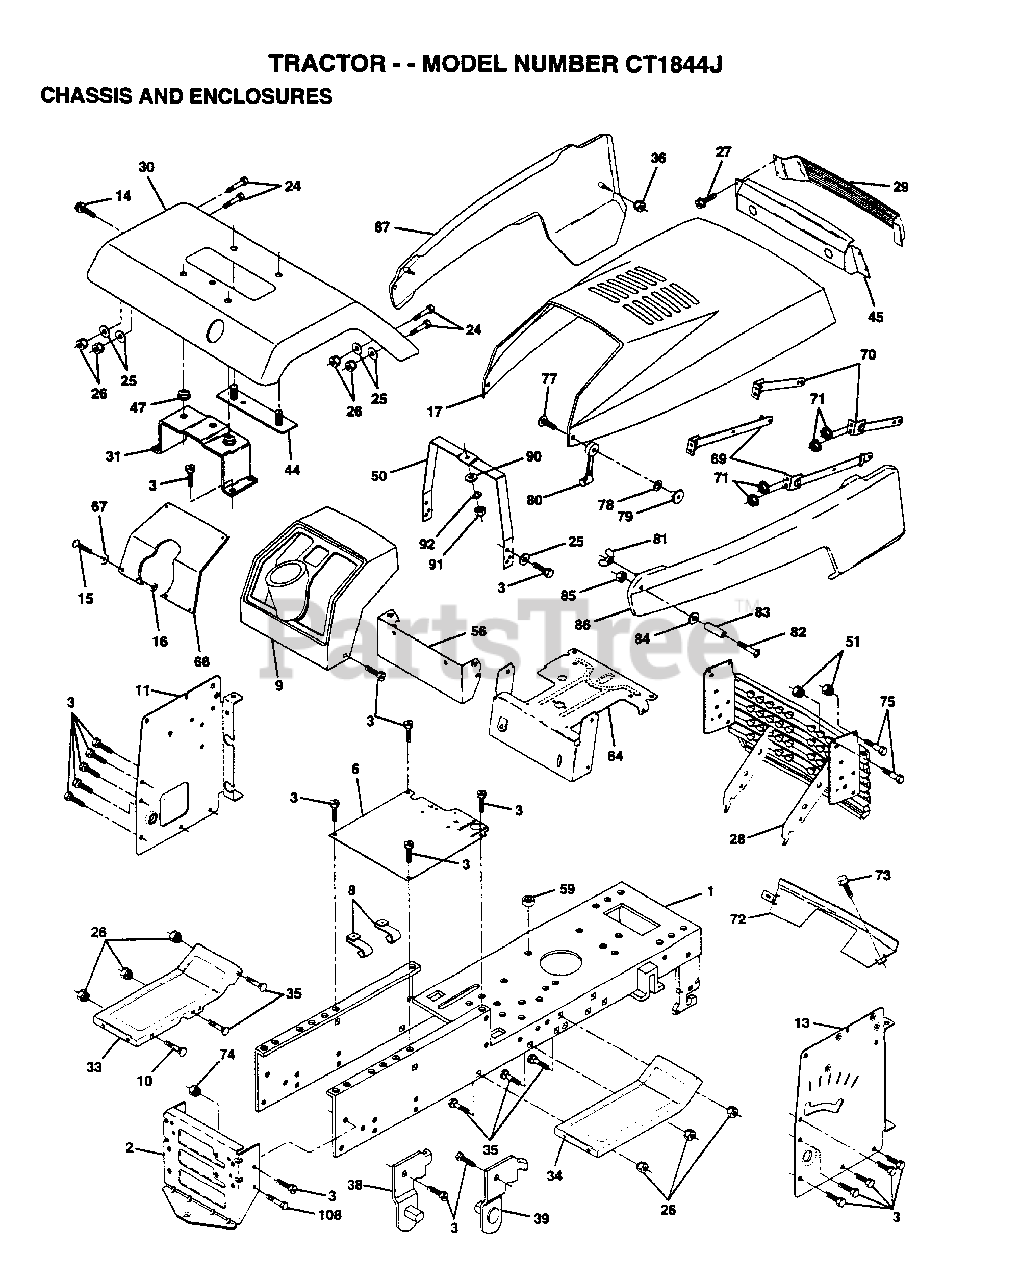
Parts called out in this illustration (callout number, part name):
1	CHASSIS.WLD.11GA
2	DRAW BAR
3	SCREW
8	"CLIP,INSULATOR"
9	DASHBOARD BLACK
11	PANEL.DASH.LH.PNT
13	PANEL.DASH.RH.PNT
14	SCREW LT
15	SCREW
24	BOLT
25	WASHER
26	NUT
29	LENS.BAR.CLEAR
30	FENDER PNT
31	BRKT.ASM.FENDER
33	FOOTREST.LH.LT/GT
34	FOOTREST.RH.LT/GT
35	BOLT
36	PAL NUT LT
38	BRACKET ASM LH
39	BRACKET ASM RH
44	STRAP ASM FENDER
47	NUT-PUSH YT
50	DASH.SUPT.YP/HUSQ
56	DASH.EXT.PNT.
66	PLATE SLKSCR YP
67	WASHER
71	NUT
72	STRAP.PNT.GRILLE
73	SCREW CRT
77	SCREW
78	LOCKWASHER
79	WELDNUT
80	HOOD LATCH T
82	SCREW
83	SPACER LT
84	WASHER
86	PANEL.SD.RH.YT/GT
87	PANEL.SD.LH.YT/GT
90	WASHER PM
92	LOCKWASHER
